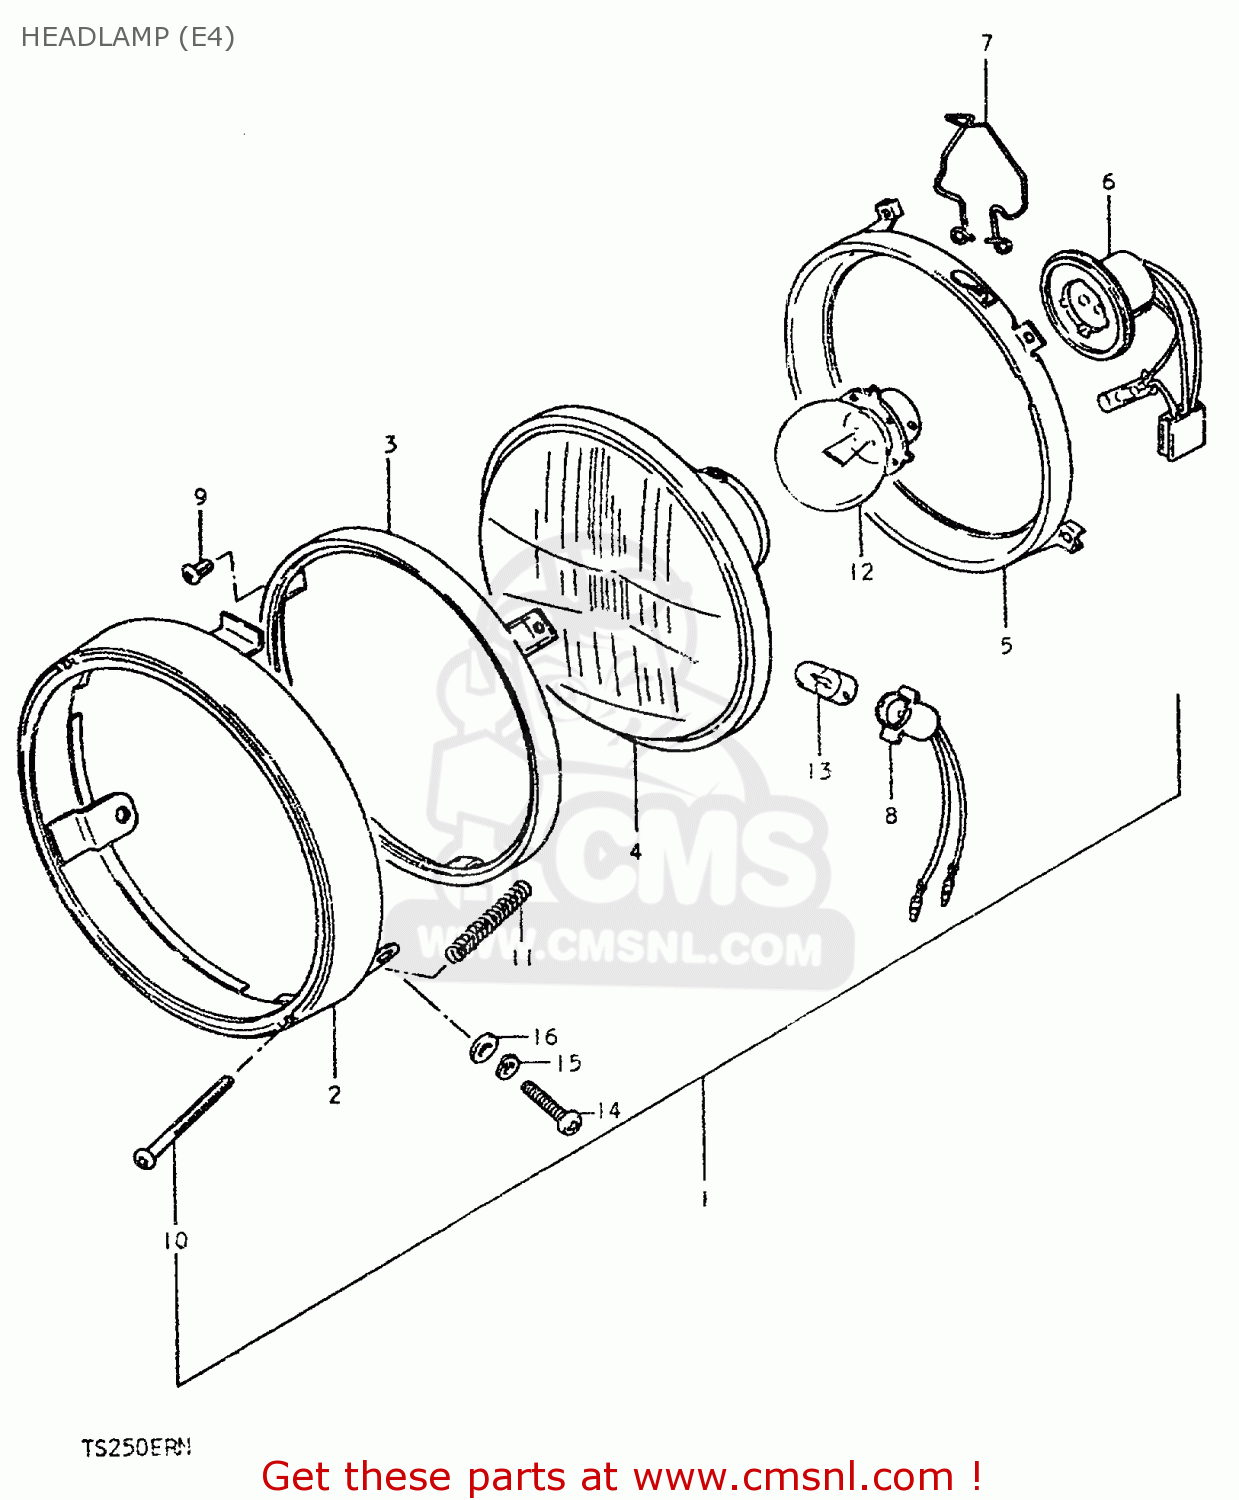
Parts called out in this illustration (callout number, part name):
1	HEADLAMP ASSY
2	RIM
3	RETAINER,HEADLAMP
4	UNIT
5	RING, MOUNTING
6	SOCKET
7	CLAMP,HEADLAMP
8	SOCKET
9	SCREW
10	SCREW,HEADLAMP ADJUST
11	SPRING,ADJUSTING
12	BULB (6V,25/25W)
13	BULB (6V,4W)
14	SCREW
15	LOCK WASHER
16	WASHER
